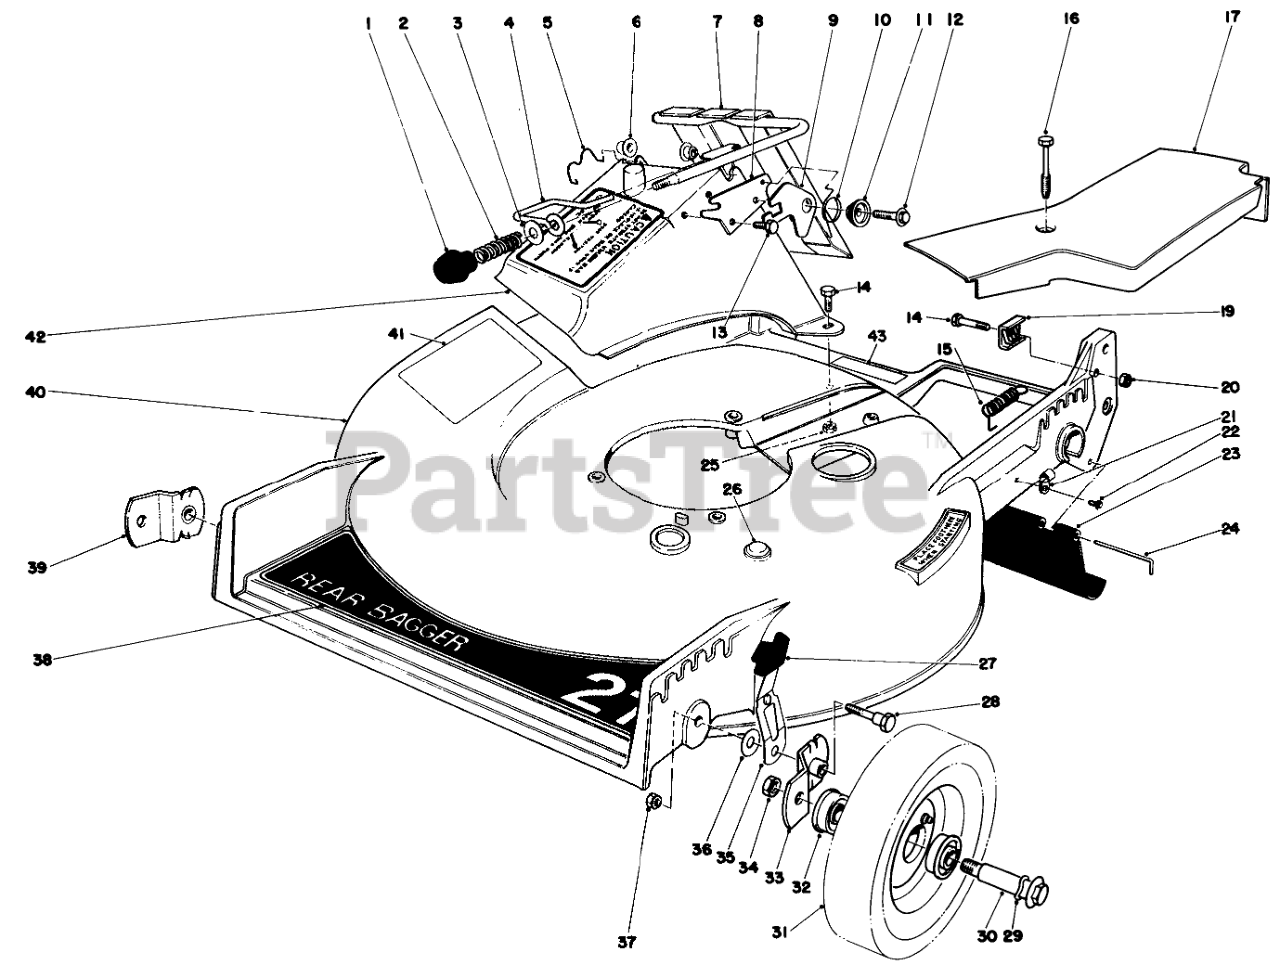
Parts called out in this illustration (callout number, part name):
2	COMPRESSION SPRING
3	WASHER-FLAT
4	DOOR LATCH
5	DOOR RETAINER
6	BUSHING-NYLON
7	DOOR & HANDLE WA
8	DOOR LATCH PLATE
9	Latch-Door
10	Spring-Torsion
11	Latch Spacer
12	Screw
13	Screw
14	SCREW-HH
15	IDLER SPRING
16	SCREW-HHFTF
17	Belt Cover
19	CLAMP-CABLE
20	NUT-JAM
21	CLAMP-NYLON
22	SCREW-HWH
23	SHIELD - TRAILING
24	Rod Shield
27	KNOB-ARM
28	PIVOT SCREW
29	SPRING WASHER
31	Wheel & Tire Assy. (Incl. Ref. #32)
32	BEARING-BALL
33	PIVOT ARM ASM A
34	Nut
35	SPRING ARM ASM (R&S)
36	WASHER-PIVOT
37	Nut
38	Decal-Deck
39	PIVOT ARM ASM B
40	Housing
41	Decal-Caution (French & Dutch)
42	DISCHARGE CHUTE B
43	Decal-Noise (French)
